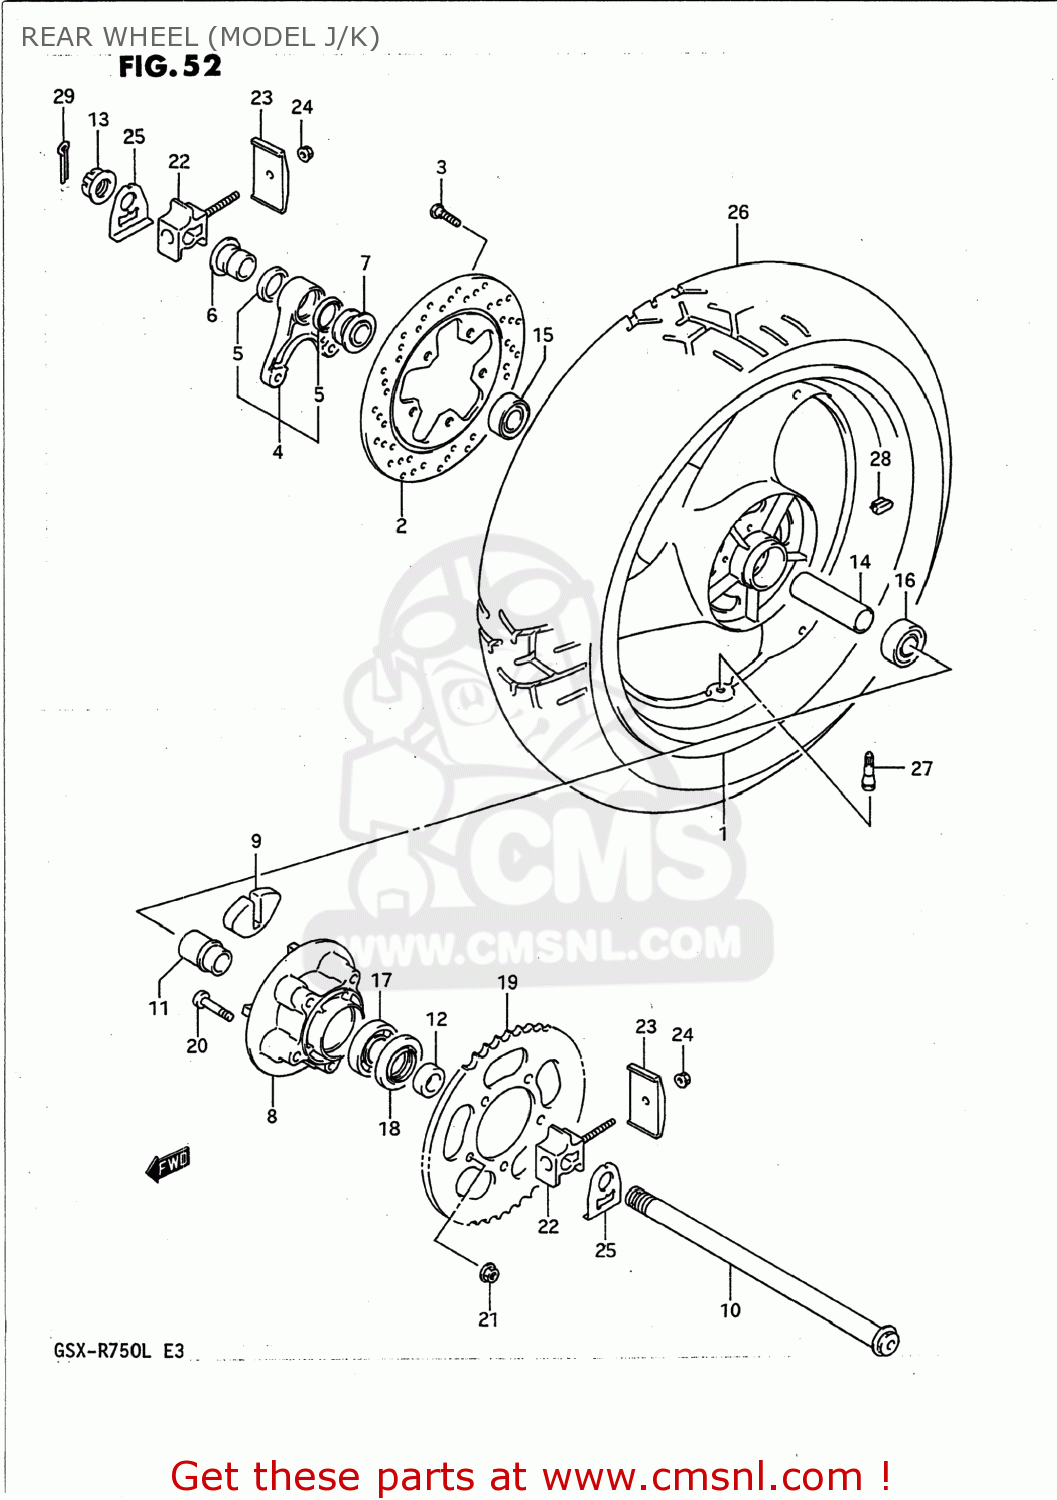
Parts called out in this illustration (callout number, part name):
1	WHEEL,REAR
2	DISC,RR BRAKE
3	BOLT
4	BRACKET,RR CALIPER
5	SEAL,OIL(28X35X5)
6	SPACER,RR CALIPER BRACKET
7	SPACER,RR AXLE,R
8	DRUM,RR SPROCKET MOUNTING
9	ABSORBER,RR HUB SHOCK
10	AXLE,RR
11	RETAINER,RR HUB BEARING
12	SPACER,RR AXLE,L
13	NUT
14	SPACER(20.8X27.2X97)
15	BEARING
16	BEARING(20X47X14)
17	BEARING(25X62X17)
18	SEAL,OIL(35X62X8)
19	SPROCKET,REAR
20	BOLT
21	NUT
22	ADJUSTER,CHAIN
23	PLATE,CHAIN ADJUSTER GEAR
24	NUT
25	WASHER,CHAIN ADJUSTER(D=20)
26	TIRE
27	VALVE,TIRE
28	BALANCER,WHEEL
29	PIN, COTTER
